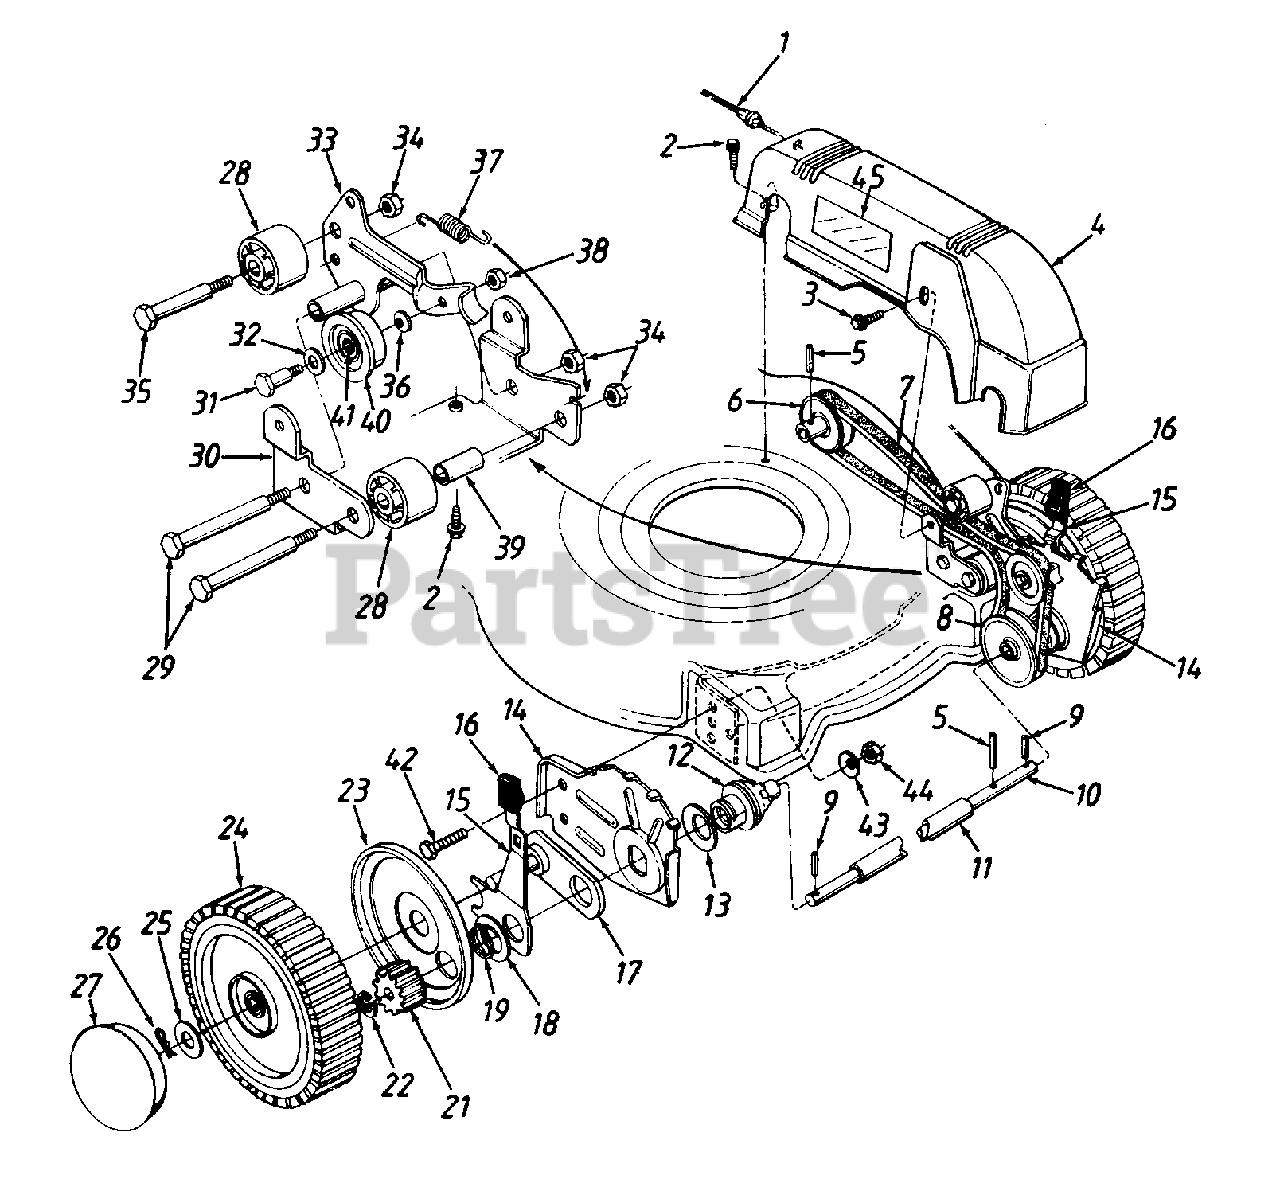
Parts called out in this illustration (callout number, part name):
1	S.P. Cable 44.75" Lg.
2	Hex Wash. Hd. TT-Tap Scr. 1/4-20 x .5" Lg.
3	Hex Wash. Hd. Tap Scr. 1/4-20 x .38" Lg.
4	Belt Cover
5	Spring Pin 3/16" Dia. x 1.25" Lg.
6	3/8" "V"-Pulley 2.75" O.D.
7	"V"-Belt
8	3/8" "V"-Pulley 2.44" O.D.
9	Spring Pin 3/16" Dia. x .875" Lg.
10	Front Axle
11	Axle Shroud
12	Front Bearing Ass'y.
13	Wave-Wash. 1.01" I.D.
14	Height Adj. Plate - R.H.
14	Height Adj. Plate - L.H.
15	Spring Lever - R.H.
15	Spring Lever - L.H.
16	Spring Lever Knob
17	Height Adj. Pivot Plate Ass'y.
18	DD Washer 1.5" O.D.
19	Snap Ring
21	14-T Spur Gear
22	E-Ring
23	Wheel Dust Cap
24	Front Wheel Ass'y.
25	Fl-Wash. .531" I.D. x 1" O.D.
26	Hairpin Clip 5/16" Dia.
27	Hub Cap
28	Idler Ass'y.
29	Shld. Bolt .374" Dia. x 1.94"
32	Fl-Wash. .39" I.D. x 1" O.D.
35	Shld. Bolt 3/8" Dia. x 1.16"
36	Bell-Wash. .265" I.D. x .75" O.D.
37	Spring Extension 1.29" Lg.
38	Hex Nut 1/4-28 Thd.
39	Spacer .385" I.D. x .625" O.D.
40	Fl-Idler 1.5" O.D.
41	Needle Brg. .375" I.D.
42	Hex Bolt 3/8-16 x .62" Lg.
43	Bell-Wash. .39" I.D. x 1.13" O.D.
44	Hex Nut 3/8-16 Thd.
45	Foil Label
